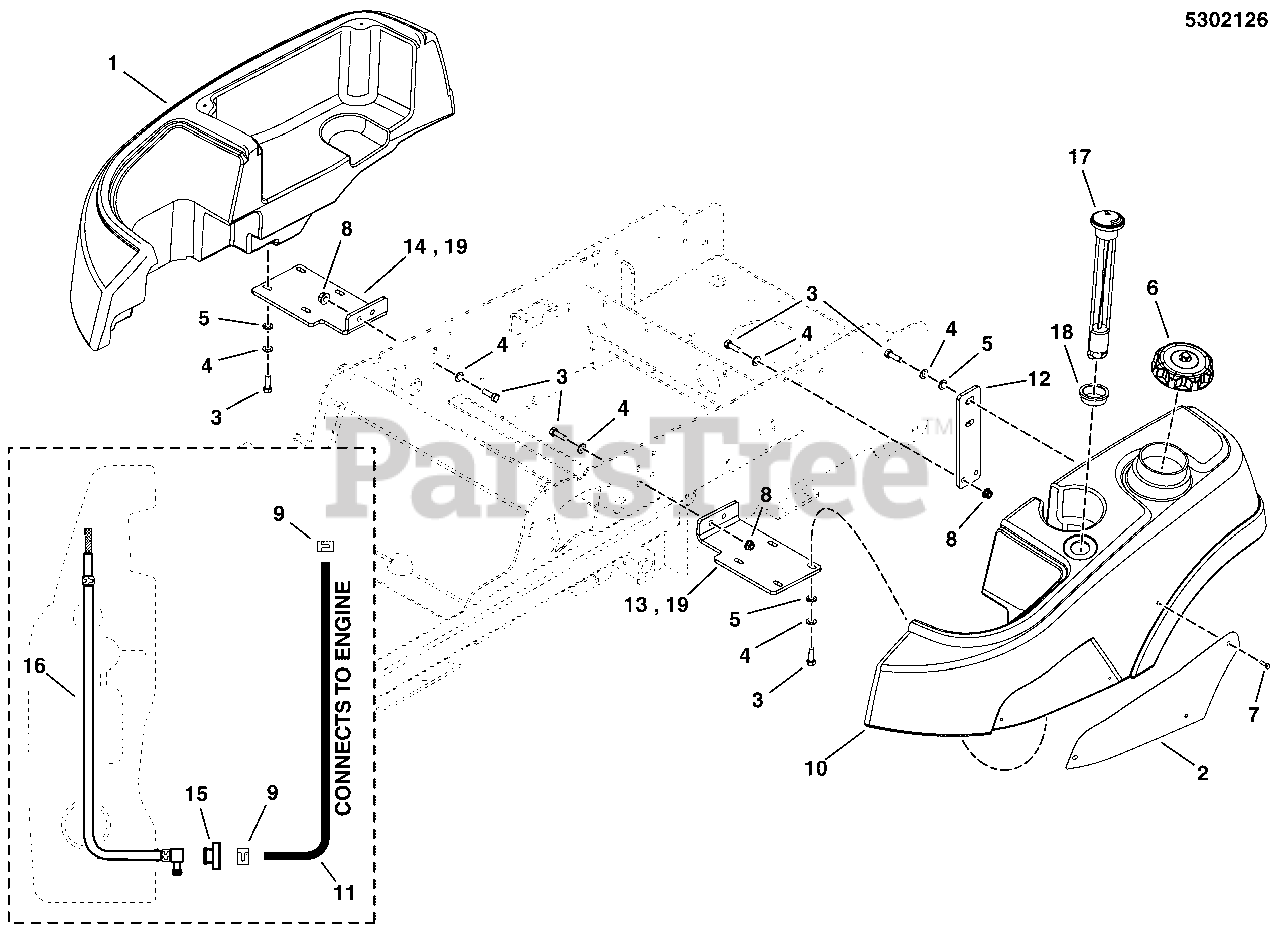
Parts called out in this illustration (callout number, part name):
1	TANK, FENDER, CONZ, RH
2	PLATE, FUEL TANK BADGE
3	BOLT, 5/16-18 X 1 GD5
4	WASHER, 5/16" SAE
5	WASHER, 5/16 LOCK YZ
6	FUEL CAP, 3-1/2", MANAGED VENT OUT, 12"
7	SCREW, #10-24 X 3/8 ALLEN BHBZ
8	NUT, 5/16-18 HEX NYLOCK FLANGE
9	CLAMP, HOSE, EXTERNAL, 1/2 - RED
10	TANK, FUEL, LH
11	HOSE, 1/4" FUEL, 20.00"
11	HOSE, 1/4" FUEL, 2.50"
12	MOUNT, FUEL TANK, REAR - BLK
13	MOUNT, FUEL TANK, FRONT - BLK
14	MOUNT, FENDER, FRONT - BLK
15	KIT, BUSHING FUEL
16	PICKUP TUBE ASM, FUEL TANK
17	GAUGE, FUEL
18	GROMMET, FUEL GAUGE
19	MOUNT, FENDER, FRONT - BLK
